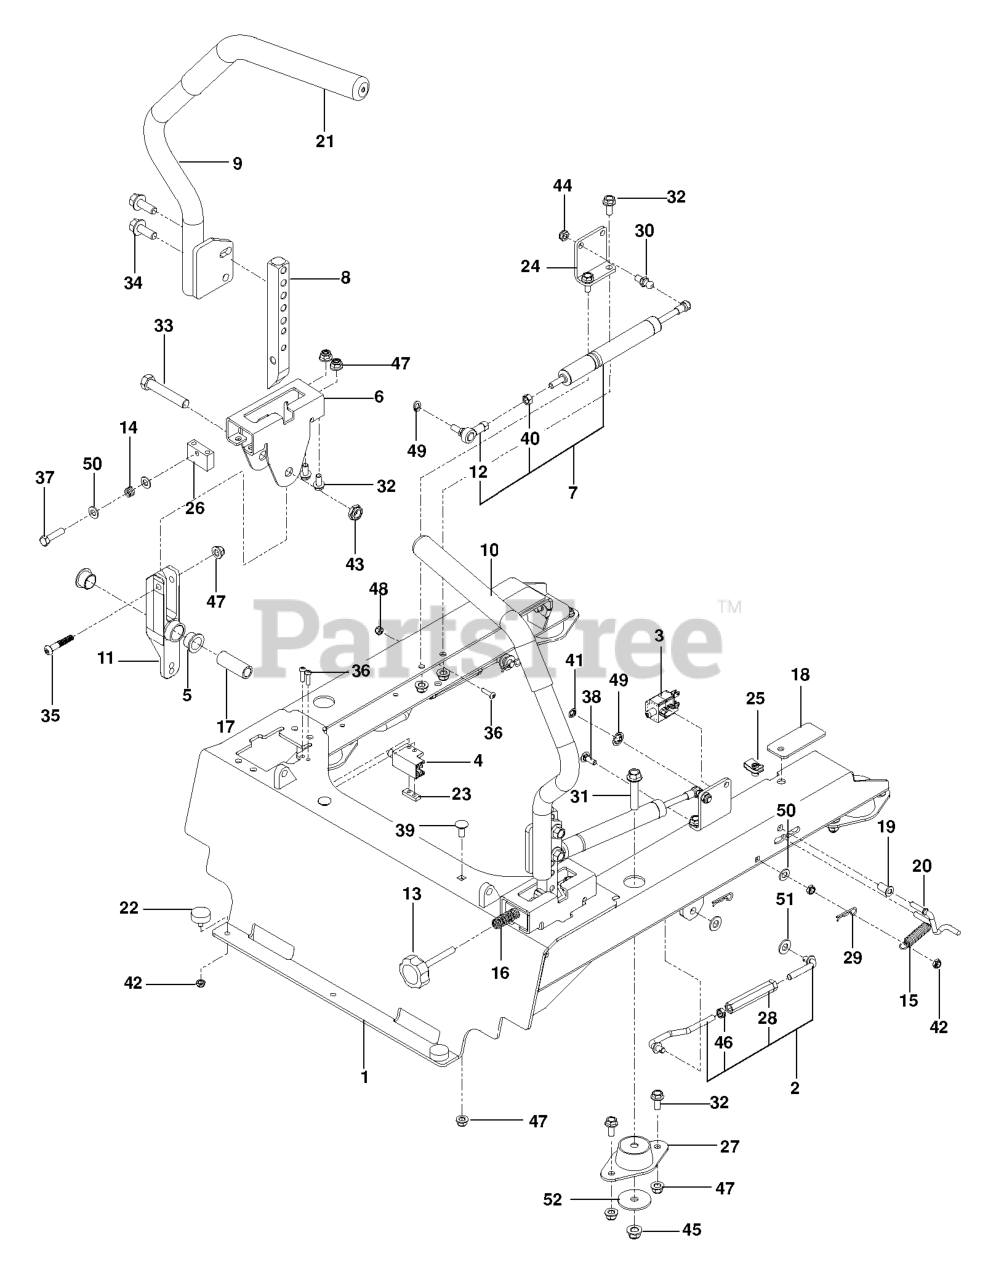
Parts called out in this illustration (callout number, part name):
1	FRAME SEAT MOUNT ORANGE
2	ASSEMBLY, SEAT STRUT
3	SWITCH, BRAKE 3P
4	SWITCH INTERLOCKT
5	BEARING, FLANGE
6	BRACKET, CONTROL
7	ASSEMBLY, DAMPENER
8	LEVER, MOTION
9	LEVER.WITH GRIP.RT
10	LEVER.WITH GRIP.LT
11	LEVER.CONTROL.SHORT
15	SPRING, EXTENSION
16	SPRING COMPRESSION 2.0
17	SPACER, PIVOT CONTROL
18	SPACER, BLK
19	BUSHING, 1/4 FLANGE
20	LINK, SWITCH
21	GRIP - DRIVE LEVER 12"
22	BUMPER, 1/4-20 STUD, 1/4
23	TAPPED PLATE
24	BRACKET.DAMPNER
25	U-CLIP 5/16-18 NUT RETAINER
26	BLOCK.TRACKING
27	MOUNT, ISO
28	TURNBUCKLE, 3/8
29	HAIRPIN #2
30	STUD.BALL.10MM
31	HHFS 3/8-16 X 2.0 GD 5
32	HHFS 5/16-18 X 3/4
33	HCS 1/2C X 2 3/4
34	HHFS 3/8-16 X 1 GRD 5 ZD
35	SCREW 5/16-18 X 1 3/4 BTN-HD
36	SCR #10-24 X .75 SKT HD BLK
37	BOLT.5/16-18X1-1/4 FULL.THREAD
38	RHSNB 1/4C X 3/4
39	BOLT 5/16C X 3/4" CARRIAGE
40	NUT M8 X 1.25 STD HEX
42	JAM NUT 1/4C (2 2 PW01)
43	NUT 1/2-13 HEX JM NYL
44	NUT 5/16 NYLOC
45	NUT 3/8-16 HEX FLG NYLOC ZD
46	NUT 3/8-24 JAM
47	5/16-18 NYLOC FLANGE NUT
48	NUT 10-24 NYLOC
49	NUT 3/8 PALNUT RTNG BLK PHOS
50	FLAT WASHER 5/16 SAE
51	WASHER 3/8 SAE FLAT
52	WASHER, 3/8 SPEC
